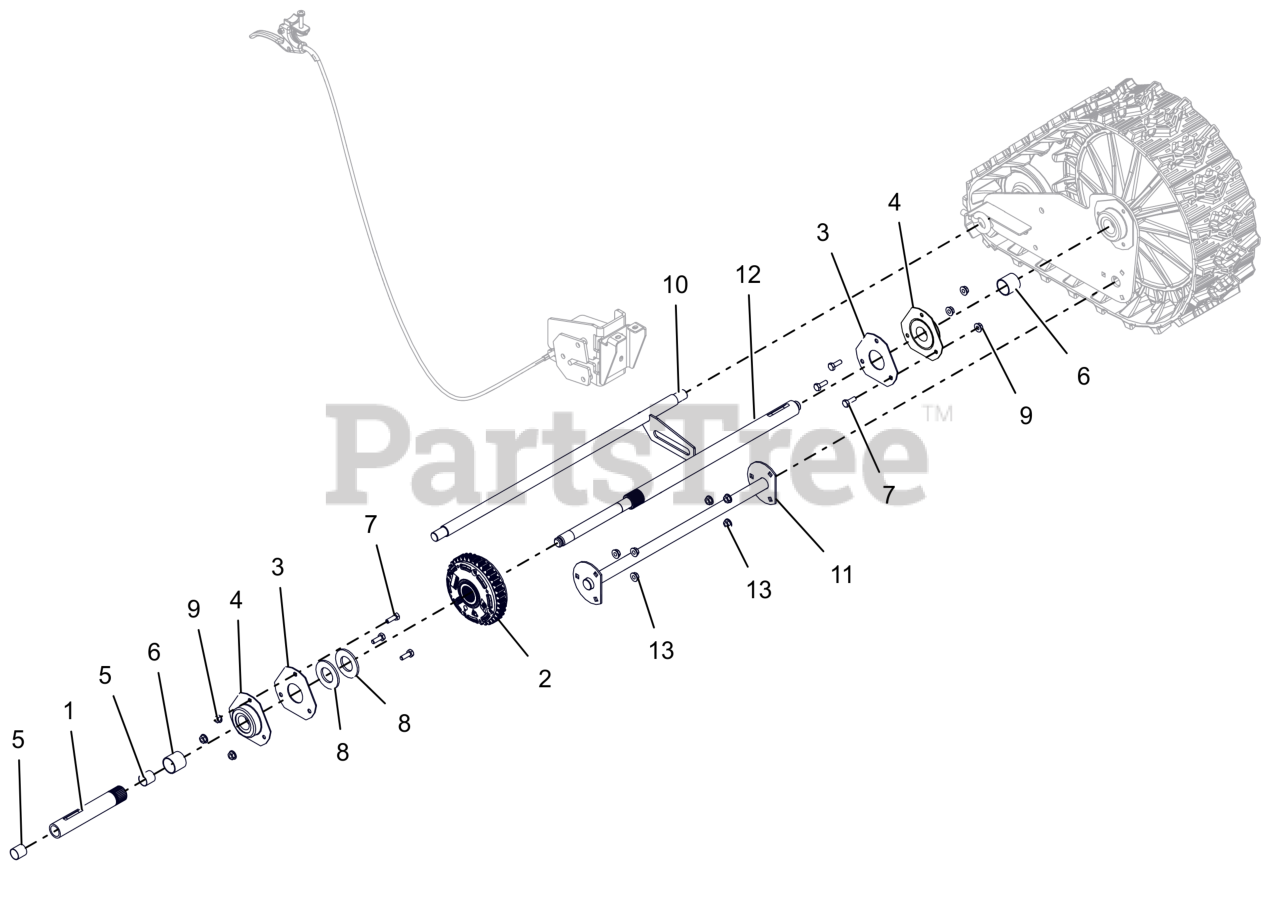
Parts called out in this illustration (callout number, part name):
1	AXLE, SHORT-W/BUSHINGS
2	DIFFERENTIAL, AUTOMATIC
3	PLATE, BEARING SPACER
4	BRG-FLG 1.003/1.000 3 BOLT
5	BSHG-SLV .706X.764X.75 BRZ
6	BSHG-SLV, 1.012X1.125X1.00
7	BLT, HEX .25-20X.75 G5 ZCC
8	WSHR, FLT 1.062X2.000X.134 ZCC
9	NUT-LK-CTR-FLG .25-20 ZC120
10	AXLE, REAR-BWT WLDMT
11	SUPPORT, FRONT-BWT
12	AXLE, LONG-TRACK DIFFERENTIAL
13	NUT-LK-TOP-FLG .250-20 GF ZCC
